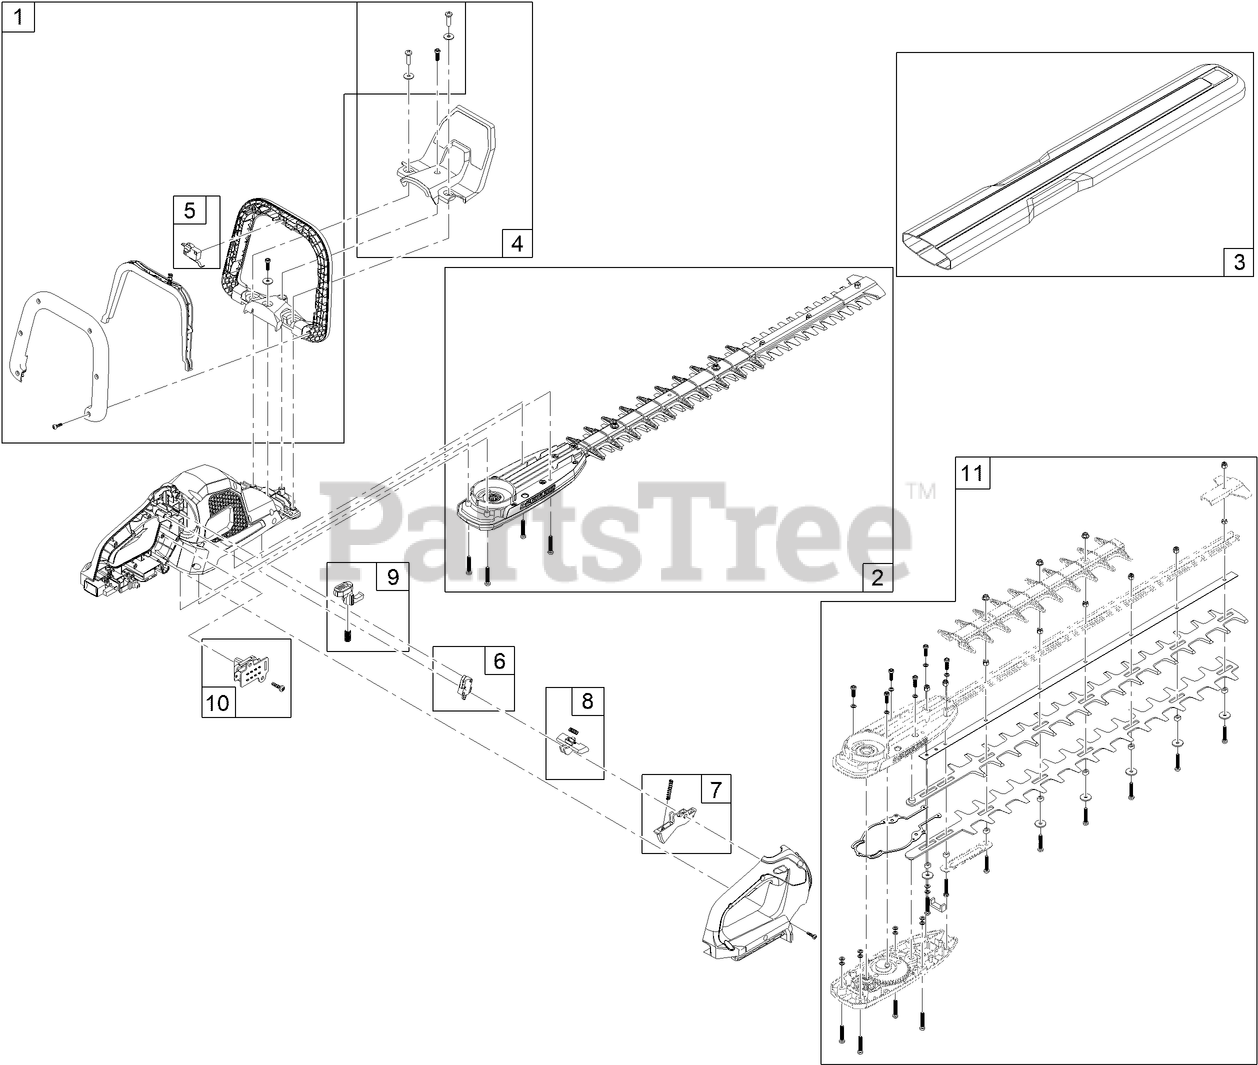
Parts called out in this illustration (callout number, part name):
1	ASSIST HANDLE ASM
2	BAR, BLADES AND GEAR CASE ASM
3	COVER-BAR
4	GUARD ASM
5	SWITCH-ASSIST HANDLE
6	SWITCH-MOTOR
7	TRIGGER-SPRING ASM
8	TRIGGER-SLIDE LOCK ASM
9	BUTTON-HANDLE ROTATION ASM
10	SWITCH-SPEED CONTROL ASM
11	HEDGE TRIMMER BLADES KIT
